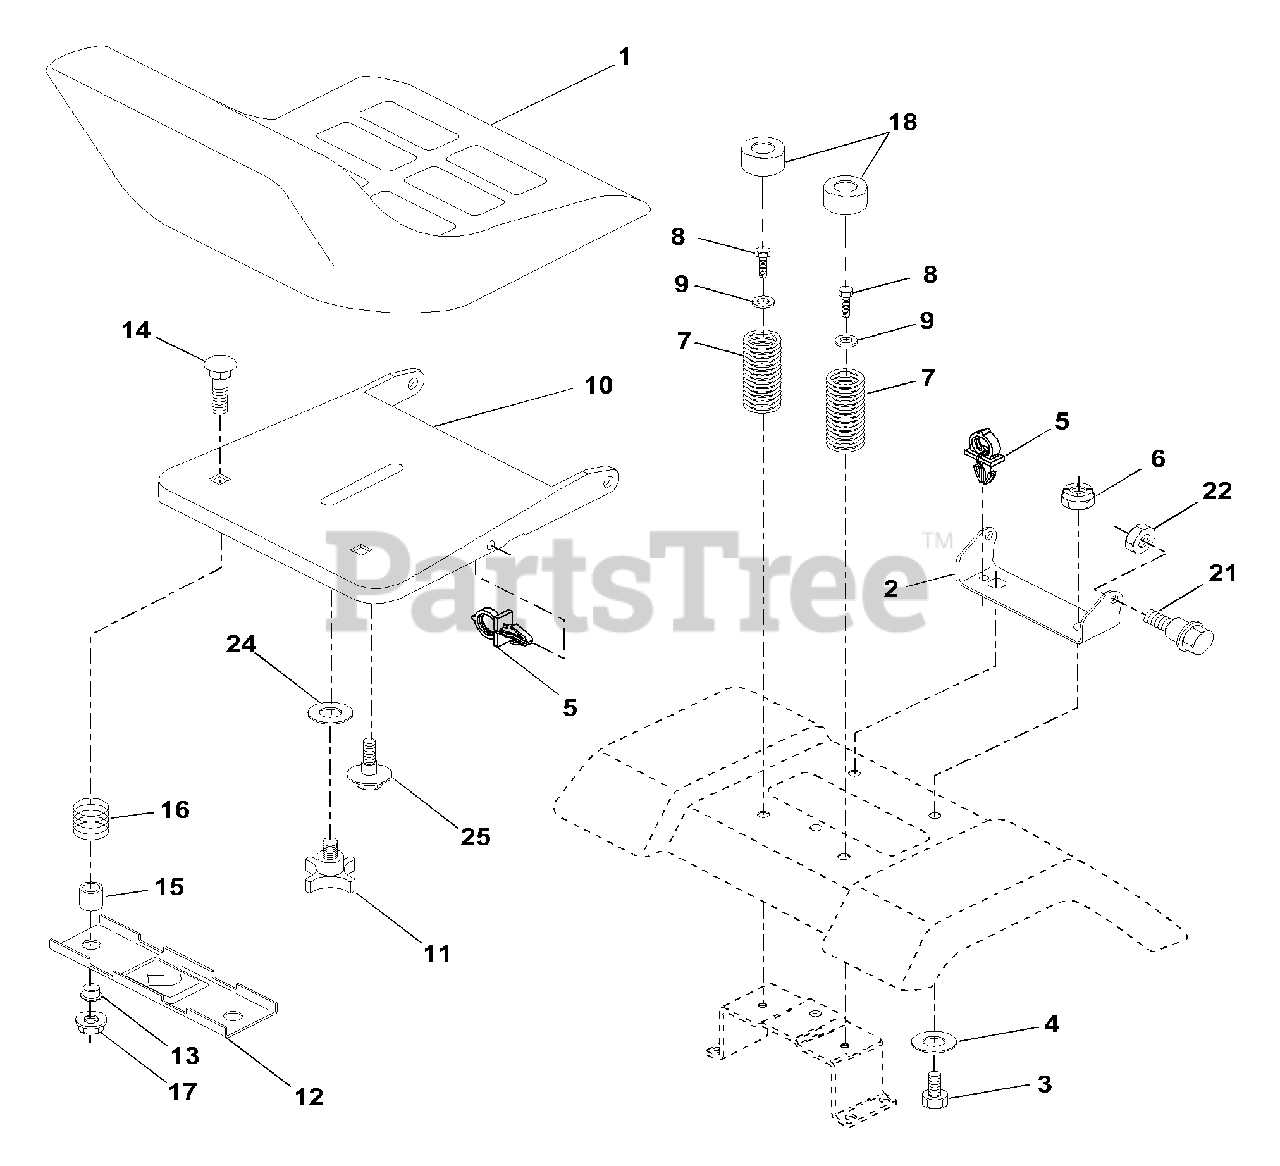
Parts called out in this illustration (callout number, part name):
1	Seat
2	Bracket Pivot Seat
3	Bolt, Hex 3/8-16unc x 1
4	Washer 13/32 X 1 X 10 Ga
5	Clip Push in Hinged
6	Nut, Crownlock 3/8-16 Unc
7	Spring Seat Cprsn
8	Screw Hwsh Thdrol 3/8-16x1
9	Washer 13/32 X 1 X 14 Ga
10	Pan Seat
11	Knob Seat 1/2-13unc
12	Bracket Mounting Switch
13	Bushing Snap
14	Bolt 1/4-20x1-3/8
15	Spacer Split
16	Spring Cprsn
17	Locknut 1/4 Gr. 5
18	Cap Spring Seat
21	Bolt, Shoulder 5/16-18 Unc
22	Nut, Lock Hex w/ins 5/16-18 UNC
24	Washer 17/32 X 1-3/16 X 12 Ga
25	Bolt, Shoulder 5/16-18 X 62
